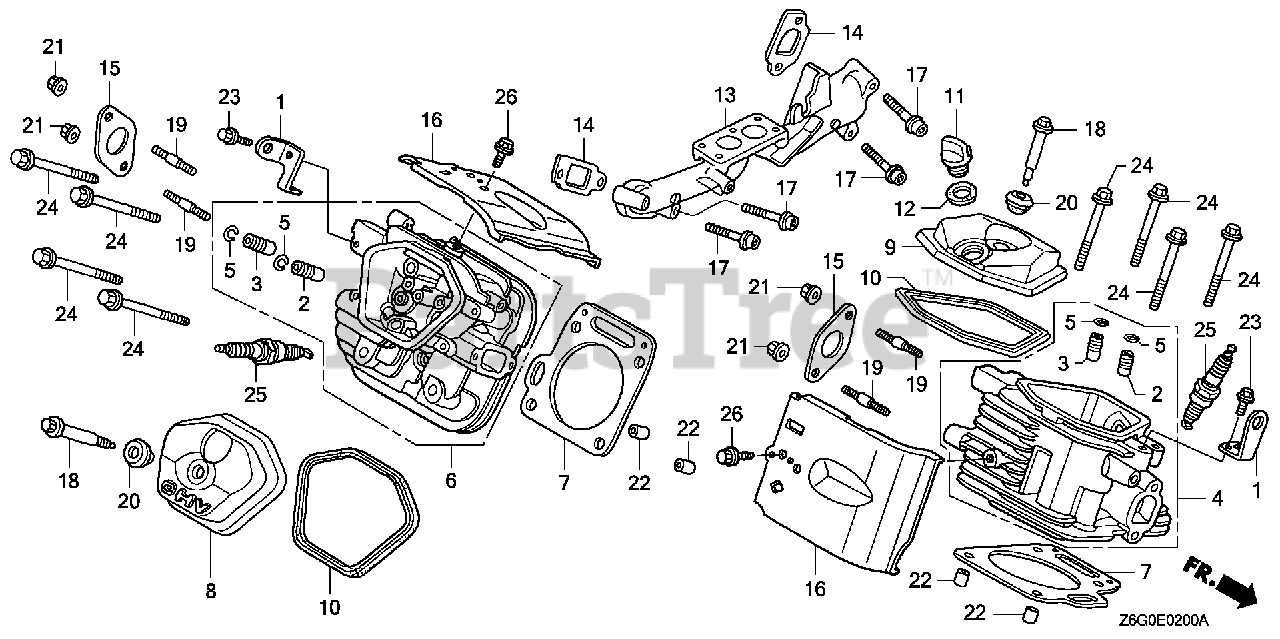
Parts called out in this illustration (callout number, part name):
1	HANGER, ENGINE
2	GUIDE, VALVE (OVER SIZE)
3	GUIDE, EX. VALVE (OVER SIZE)
4	CYLINDER HEAD (#1)
5	CLIP, VALVE GUIDE
6	CYLINDER HEAD (#2)
7	GASKET, CYLINDER HEAD
8	COVER, HEAD
9	COVER, HEAD FILLER
10	GASKET, HEAD COVER
11	CAP, OIL FILLER
12	GASKET, OIL FILLER CAP
13	MANIFOLD, IN.
14	GASKET, IN. MANIFOLD
15	GASKET, EX. PIPE
16	SHROUD, HEAD
17	BOLT, SOCKET (8X45)
18	BOLT, HEAD COVER
19	BOLT, STUD (8X22)
20	WASHER, HEAD COVER
21	NUT, FLANGE (8MM)
22	PIN, DOWEL (12X20)
23	BOLT, FLANGE (8X20)
24	BOLT, FLANGE (10X80)
25	SPARK PLUG (BPR2ES) (NGK)
25	SPARK PLUG (J14CR-U) (DENSO)
25	SPARK PLUG (ZGR4A)
25	SPARK PLUG (J16CR-U) (DENSO)
25	SPARK PLUG (ZGR5A)
26	BOLT, FLANGE (6X14) (CT200)
